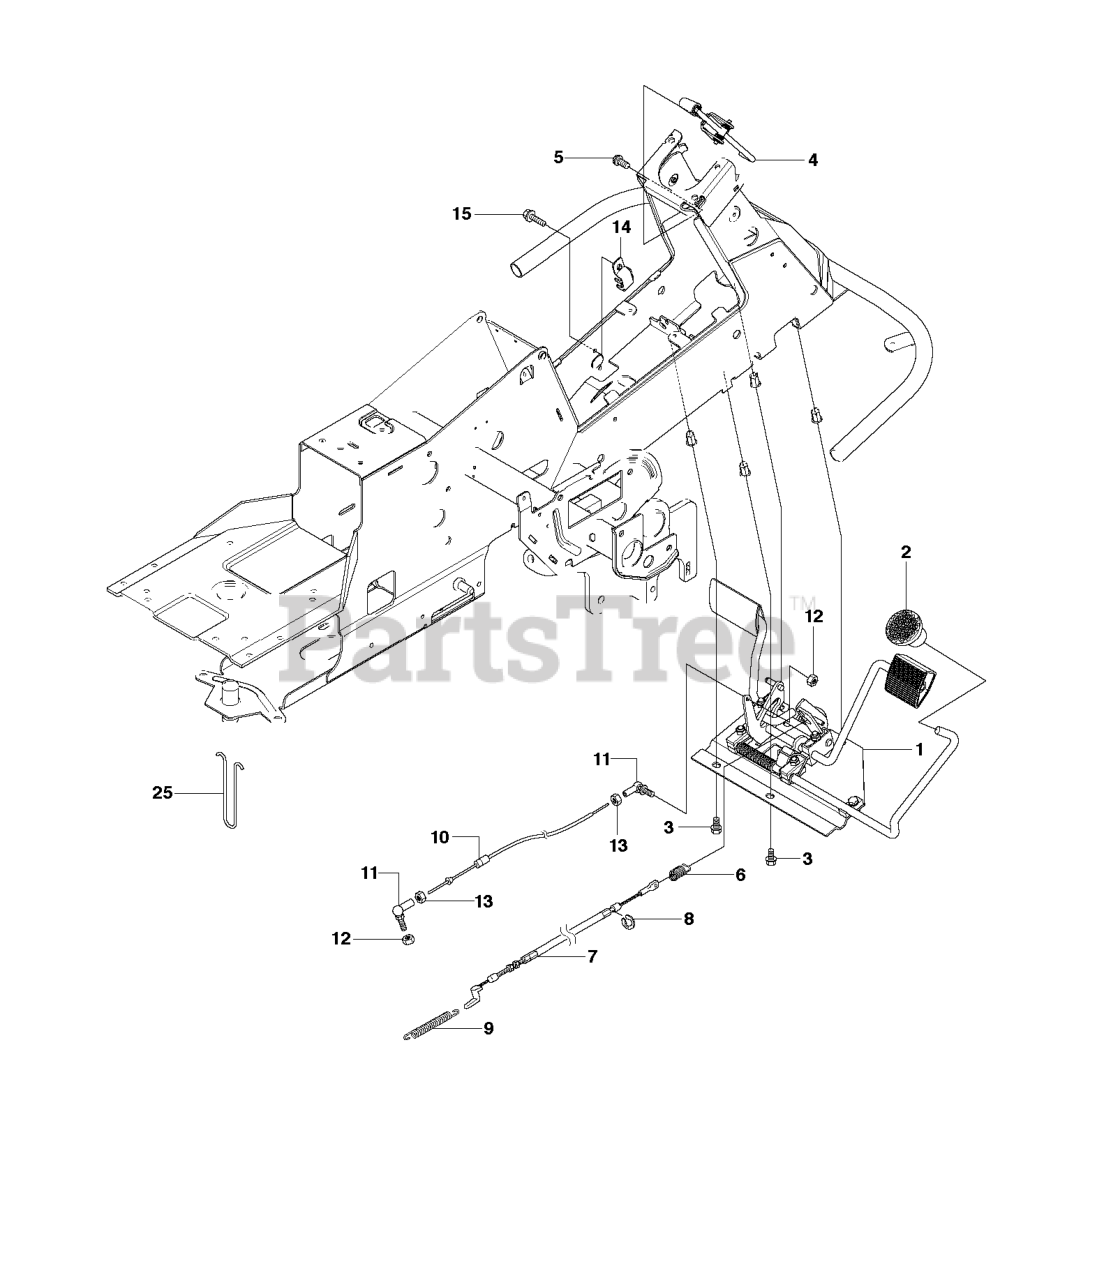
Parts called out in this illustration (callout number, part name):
1	PEDAL ASSEMBLY
2	KNOB
4	BRAKE LEVER ASSY
7	RP WIRE
10	CONTROL CABLE
11	CONNECTOR
12	LOCKNUT M5
25	CABLE HOLDER
